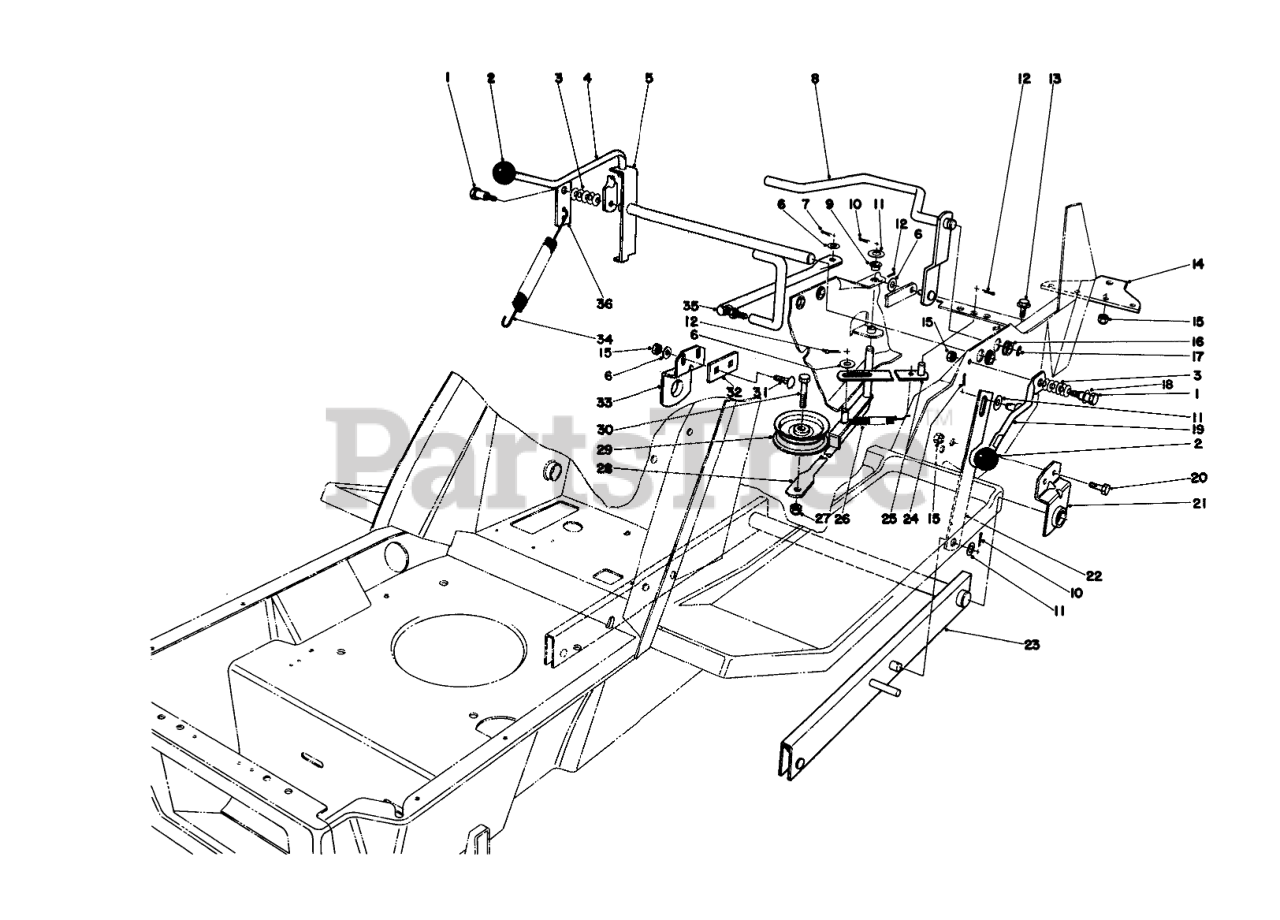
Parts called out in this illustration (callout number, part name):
1	Shoulder Bolt
2	Knob
3	Belleville Washer
4	SHIFT LEVER BO
5	Shim Lever
6	WASHER-PLAIN
7	PIN-COTTER
8	CLUTCH ACTUATOR WA B
9	BUSHING-NYLINER
10	PIN-COTTER
11	WASHER-FLAT
12	PIN-COTTER
13	SCREW-HHF
14	HITCH PLATE R
15	NUT-LOCK, CONE
16	Nyliner
17	E-RING
18	Washer
19	HOC HANDLE WA B
20	SCREW-HH
21	Retainer-Pivot Bar L.H.
22	H.O.C. STRAP B
23	Bar-Pivot
24	PIN-COTTER
25	SPRING RET WA B
26	DECK TENSION SPRNG O
27	NUT-LOCK, CONE
28	IDLER ARM WA BO
29	IDLER PULLEY
30	SCREW-HH
31	BOLT-CARR
32	SPACER
33	Retainer-Pivot Bar R.H.
34	TRACTION SPRING
35	SHIFT ARM BO
36	BRKT-COBALANCE SPRING
